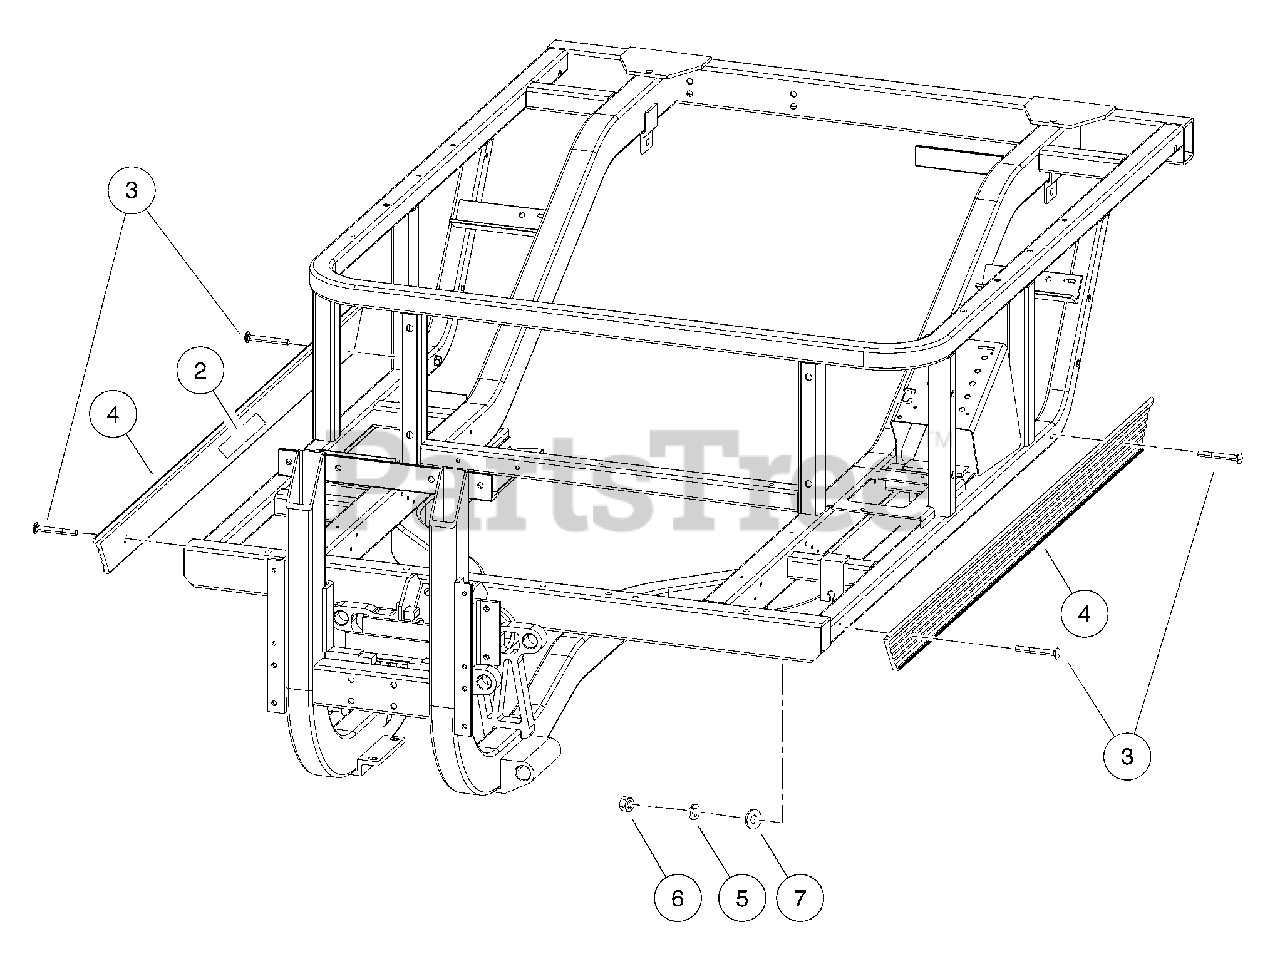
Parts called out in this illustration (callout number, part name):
1	Instl, Stringer, Black
2	Tape, 3M VHB 4950
3	Bolt, 3/8-16 X 3, Carriage Blk
4	Stringer, Side, 134925, Black
5	Washer, Lock, Hel Sp 3/8 Reg
6	Nut, Hex 3/8-16
7	Washer, 3/8 Type B Flat
